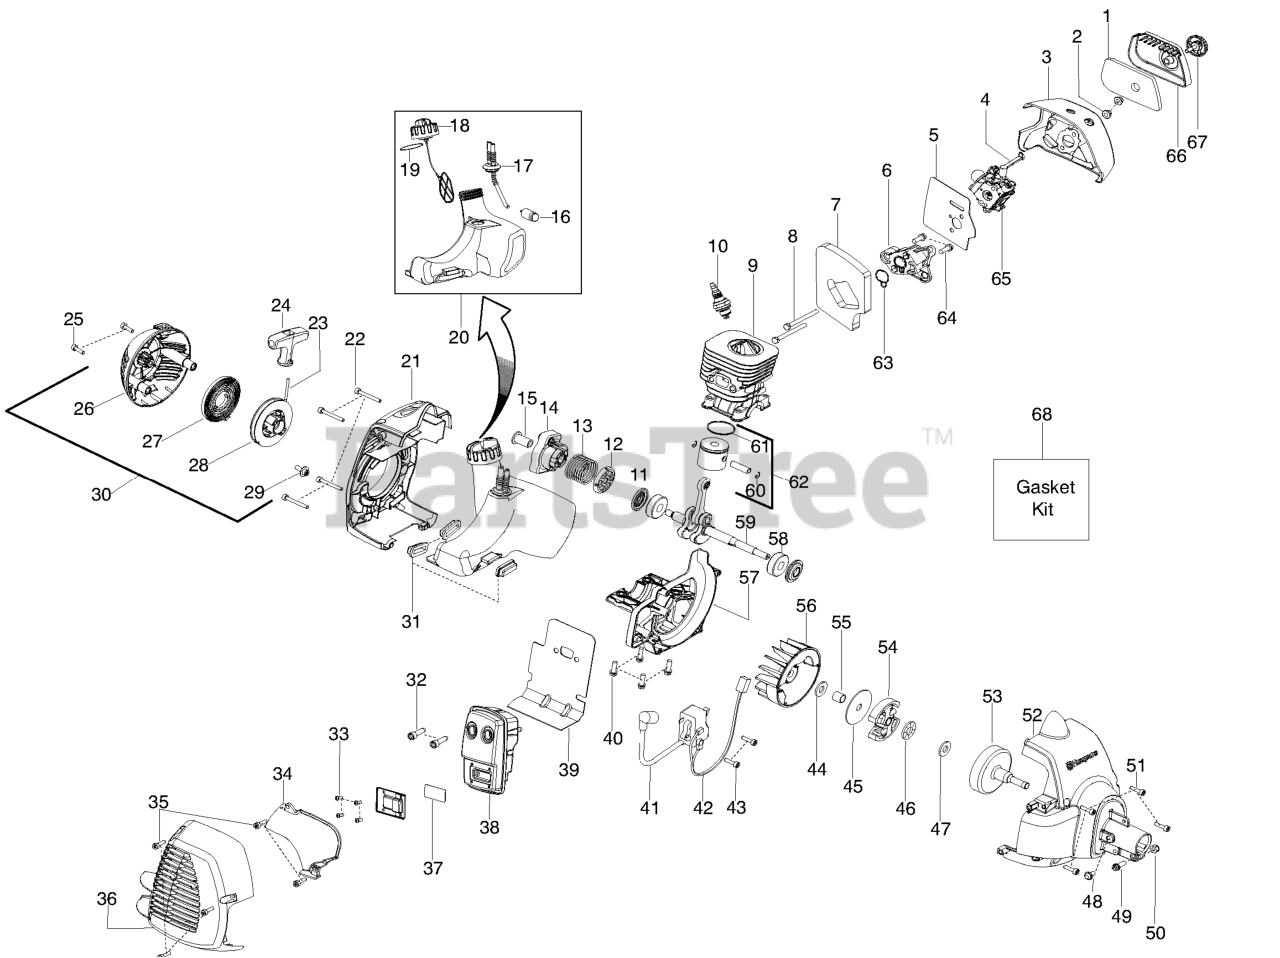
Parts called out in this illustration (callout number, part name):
1	FILTER AIRBOX
3	RP_AIR BOX
4	CHOKE LEVER
5	KIT GASKET CARB
6	CARB ADAPTOR
7	KIT GASKET 28CC
8	BOLT CARB ADAPTOR
9	CYLINDER
10	Plug-Spark (RCJ-8Y)
11	KIT SEAL CRANKSHAFT
12	WASHER STARTER
13	SPRING STARTER CUP
14	ASSY STARTER CUP
15	COUPLING STARTER
16	FUEL PICK-UP ASSY
17	KIT FUEL LINE
18	ASSY-CAP W/RETAINER
19	KIT GASKET 28CC
20	FUEL TANK ASSY
21	REAR SHROUD
24	STARTER HANDLE GRAY
25	SCREW M5-0.8X30MM
26	STARTER HOUSING
27	%KIT STARTER SPRING
28	KIT STARTER PULLEY
30	ASSY-STARTER HSG.
31	ISOLATOR FUEL TANK
32	BOLT MUFFLER
33	SCREW-10-16 X 1/2 HI-LO
34	SHIELD HEAT
35	SCREW M4 X 1.75 PT 16MM
36	GUARD-MUFFLER
37	KIT SPARK ARRESTOR SCREEN
38	ASSY-MUFFLER
39	KIT GASKET 28CC
40	SCREW-M5-0.8 X 25MM(TAP)
41	IGNITION MODULE MBU-7
42	ASSY MODULE LEAD WIRE
43	SCREW M4 X .70 TT 16MM
44	WASHER CLUTCH
45	WASHER-CLUTCH
46	BEARING THRUST
47	WASHER THRUST
50	LOCKNUT-HEX 10-24
51	SCREW M4 X .70 TT 16MM
52	FAN HSG ASSY
53	Assy-Clutch Drum
54	%KIT CLUTCH ASSY
55	SPACER FLYWHEEL
57	CRANKCASE CASTING
58	BEARING RADIAL BALL (6201)
59	KIT CRANKSHAFT ASSY
60	WRIST PIN RET.
61	RING PISTON
62	KIT PISTON 28CC TRIMMER
63	KIT GASKET 28CC
64	SCREW-M5-0.8 X 25MM(TAP)
65	Kit-Carb.
66	COVER-AIR BOX
67	KNOB ASSY AIRBOX COVER
68	KIT GASKET 28CC
